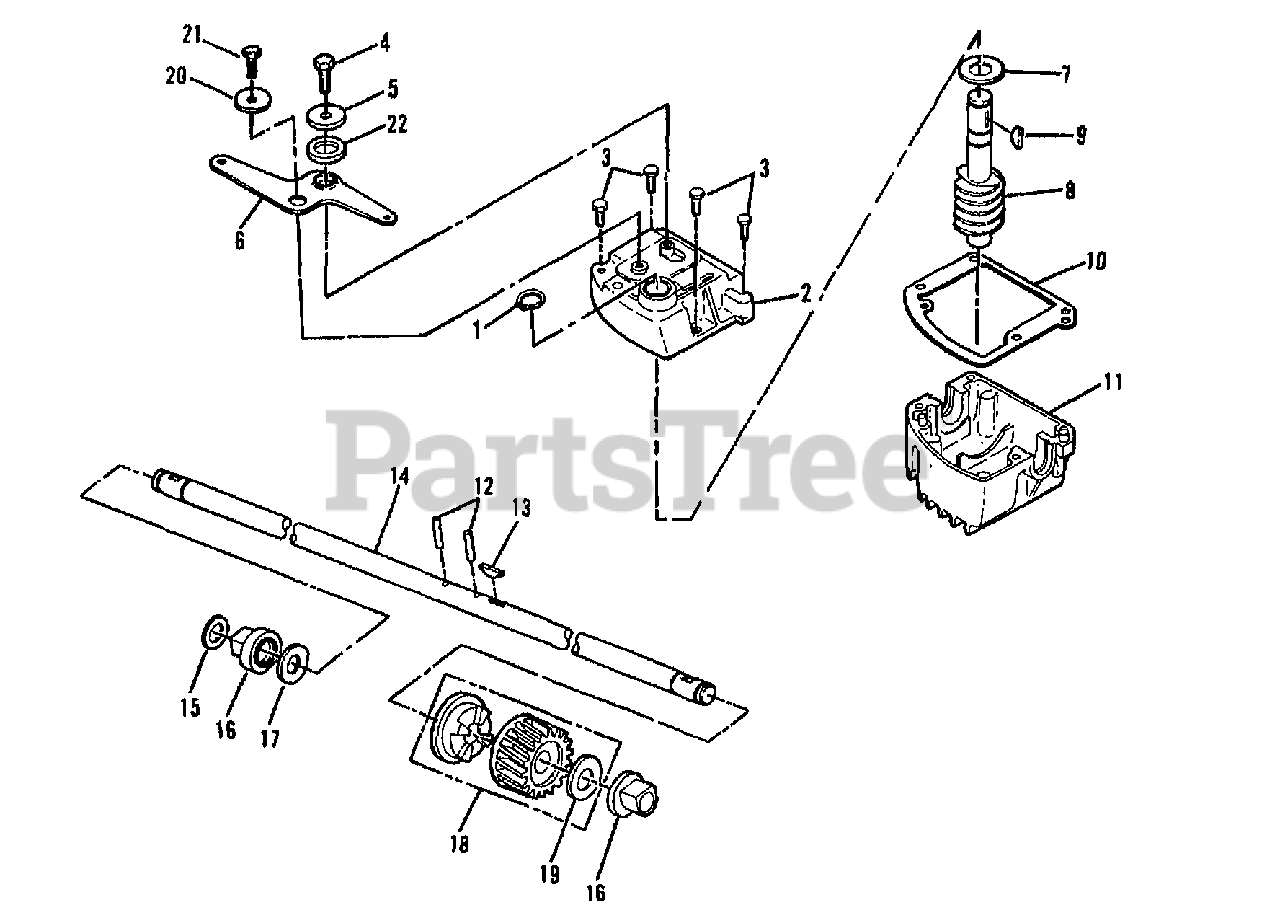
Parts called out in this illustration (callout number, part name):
1	RING-RETAINING
2	ASSM-HOUSING
3	HEX S.T. NO. 8-32 x 1/2" BOLT
4	SCR-TRUSS #10-24 X 5/8
6	LEVER-CLUTCH
8	SHAFT-INPUT
9	KEY-WDRF
11	ASSM-HOUSING
13	KEY-HI PRO
14	SHAFT-OUTPUT
16	ASSM-BRG & SEAL
18	HELICAL GEAR & CLUTCH DOG ASSEMBLY, KIT
20	WASHER-.505X.22X.05 (TRANSMISSION 1747891)
21	SCREW, TAPPING 10-24 x 1/2 (TRANSMISSION 1747891)
22	FOAM SEAL
